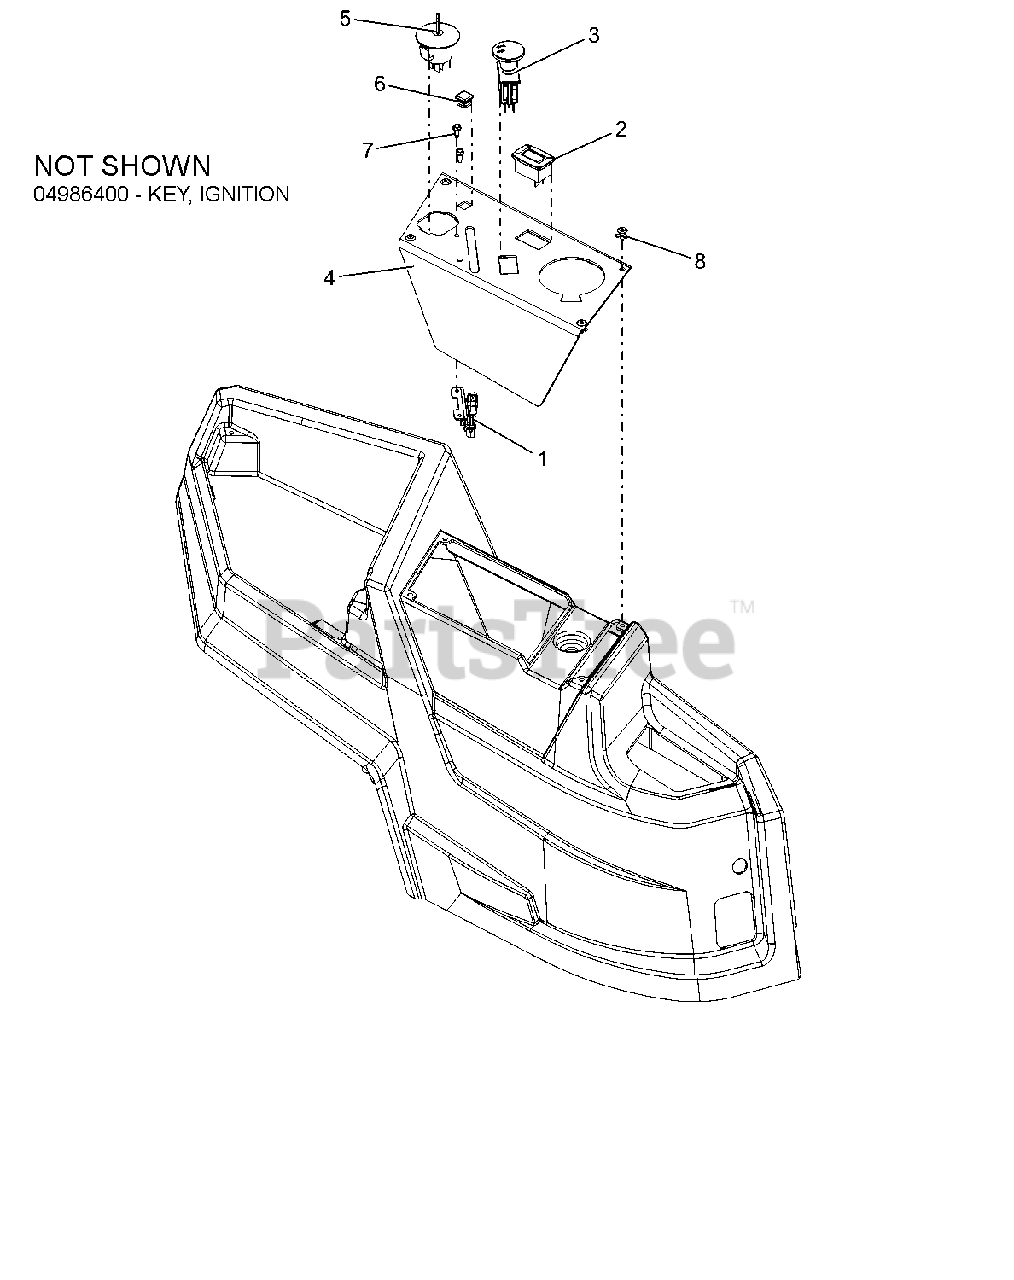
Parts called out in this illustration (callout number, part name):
1	CABLE, THROTTLE LH 90DEG 33"
2	METER, HOUR W/MAINTENANCE
3	SWITCH, CLUTCH YELLOW(W/GRAPHIC)
4	PANEL, CONTROL (RED)
5	SWITCH, IGNITION -4 POS. SNAP IN
6	PLUG, 5/8" SQ BLACK (14-20 GA)
7	SCR-TAP 10-24X.50 HWH TR YWZC
8	RVT-POP .195 PLASTIC
